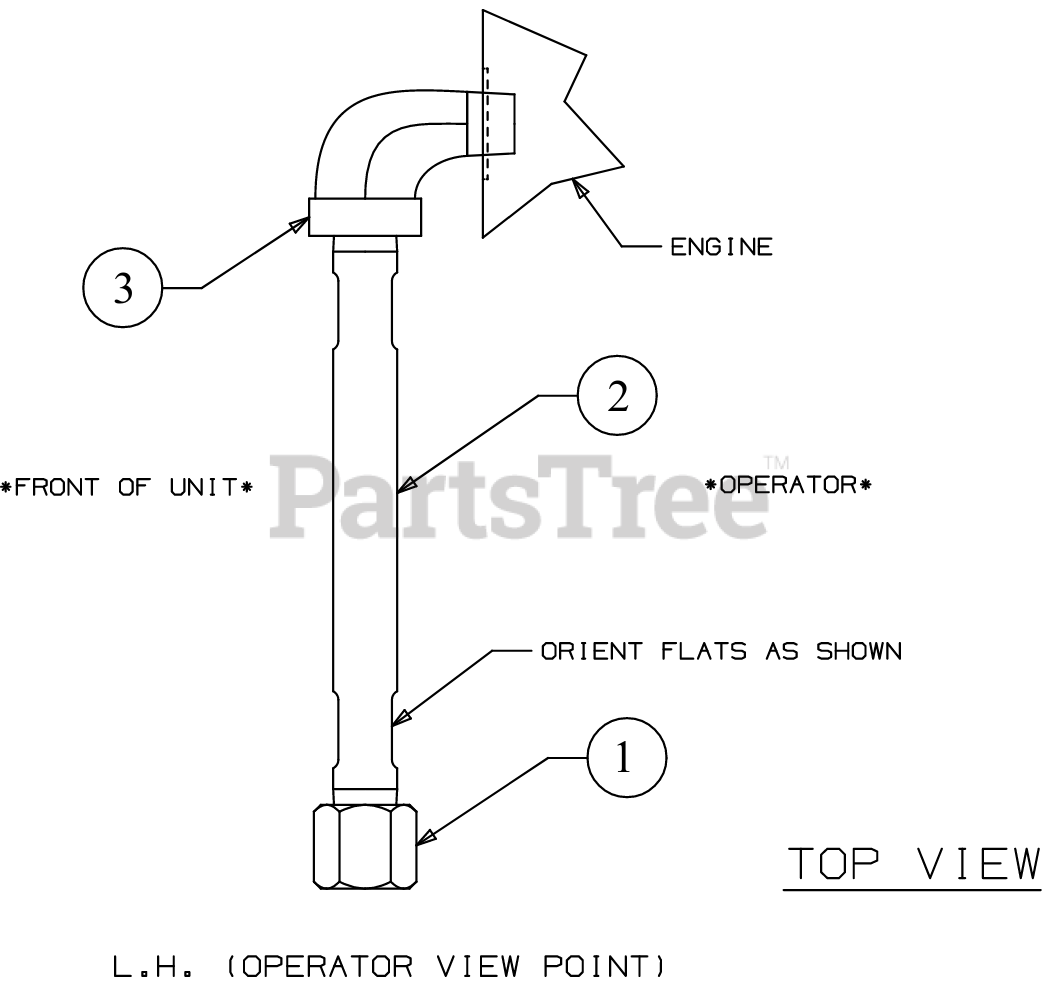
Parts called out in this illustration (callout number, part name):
1	END CAP
2	STRAIGHT PIPE 1/8-27
3	ELBOW ADAPTER
